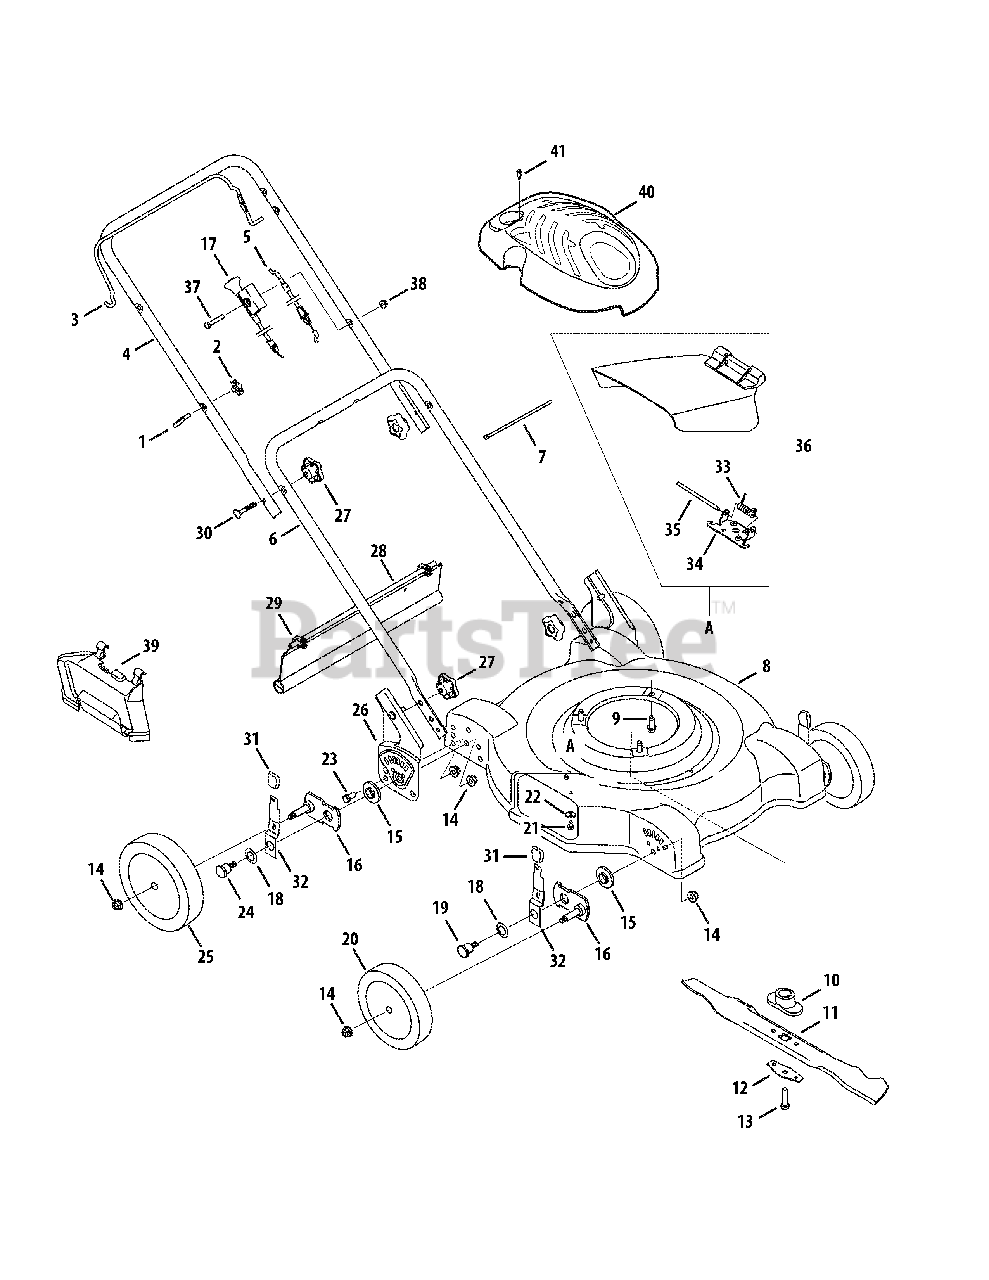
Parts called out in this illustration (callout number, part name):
1	Eye Bolt
2	Wing Nut
3	Blade Control Handle
4	Upper Handle
5	Control Cable
7	Cable Tie
8	Deck Assembly, 22"
9	TT Screw, 3/8-16 x 1.0
10	Blade Adapter
11	Standard Blade, 22"
11	Mulching Blade, 22"
12	Blade Bell Support
13	Screw, 3/8-24 x 1.5
14	Lock Nut, 3/8-16
15	Height Adjuster Bearing
16	Pivot Arm
17	Choke Cable
18	Bell Washer, .760 OD x 1.25 OD
19	Shoulder Screw
20	Front Wheel, 7 x 1.8, Bar
21	TT Screw, 1/4-20 x .5
22	Bell Washer, .265 ID x .75 OD
23	Screw, 3/8-16 x .75
24	Shoulder Screw
25	Rear Wheel, 8 x 1.8, Bar
26	Handle Bracket Assembly, RH
26	Handle Bracket Assembly, LH
27	Star Knob
28	Trailshield
29	Hinge Clip
30	Carriage Bolt, 5/16-18 x 2
31	Knob
32	Lever
33	Torsion Spring
34	Chute Hinge
35	Hinge Pin
36	Hinged Chute Deflector Ass’y.
37	Screw, 1/4-20 x 1.50
38	Nut, Flange Lock, 1/4-20
39	Mulching Baffle
40	Engine Shroud
41	Screw, HL, #12-16 x 1.00
